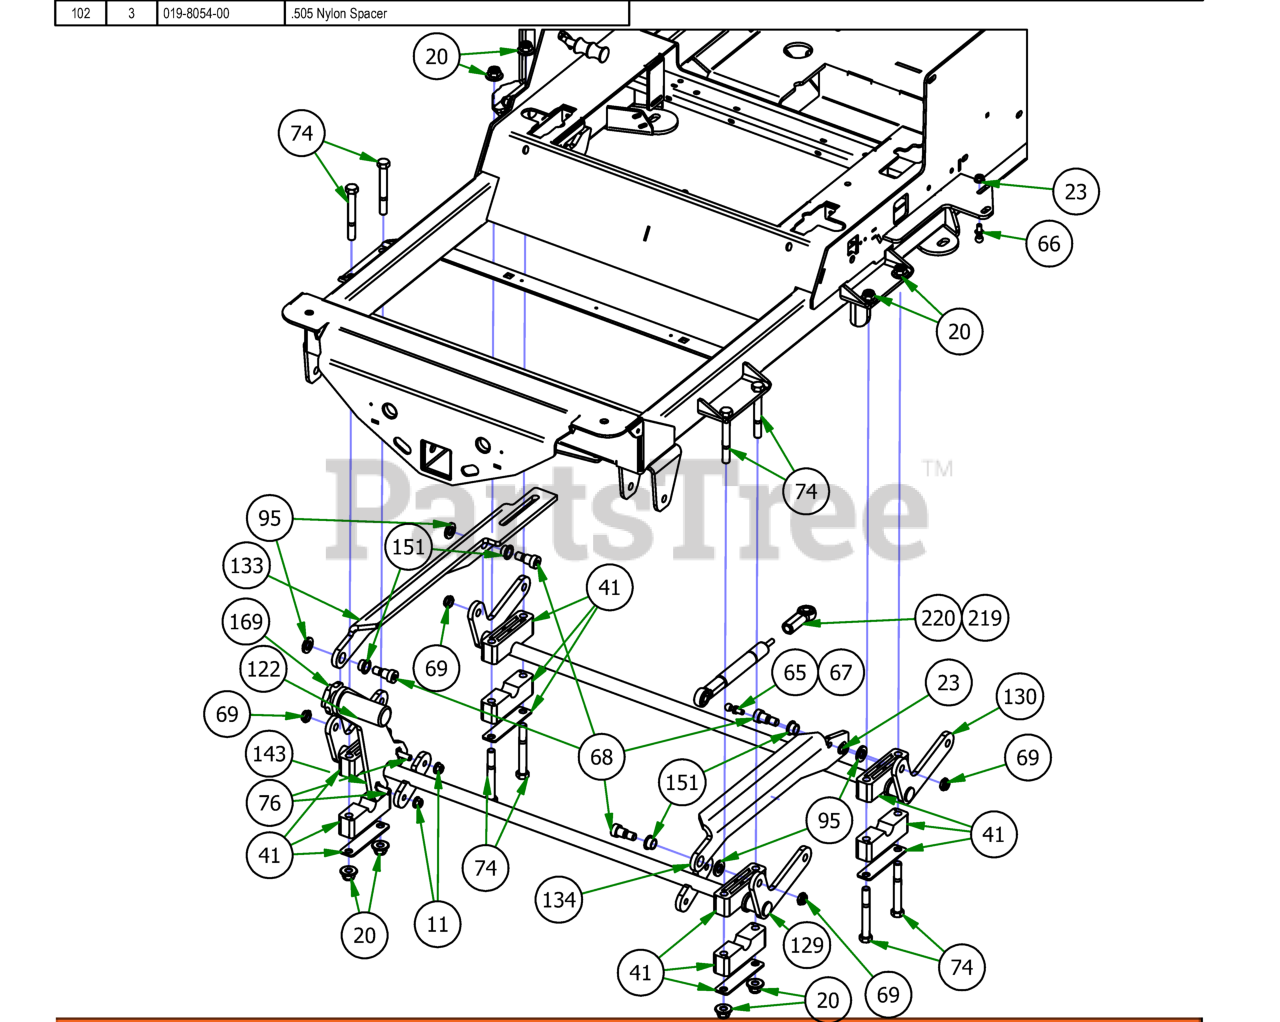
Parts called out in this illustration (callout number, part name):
11	3/8-16 NYLON INSERT FLANGE LOCKNUT (GR.F) ZINC
20	1/2-13 NYLON INSERT FLANGE LOCKNUT ZINC
23	5/16" Flange Nut
41	Pillow Block Assembly
65	13mm Damper Ball Stud-Steering
66	10mm Damper Ball Stud-Steering
67	10mm Damper Ball Stud-XP Linkage
68	5/8'' x 5/8'' Shoulder Bolt
69	1/2" Nylcock Nut (1/2 Jam)
74	1/2" x 4" Bolt (Grade 8)
76	3/8" x 1 1/4" Carriage Bolt
95	.635 ID X 1.120 OD X .140 THICK FLAT WASHER NYLON
122	Knurled Pedal
129	2019 Outlaw Actuator - Front
130	2019 Outlaw Actuator - Rear
133	2019 Actuator Linkage - Right
134	2019 Actuator Linkage - Left
143	Foot Lift Upright Lever
151	Bronze Bushing - SF - 2024-8
169	Foot Pedal Knob 1/2-13
204	2019 Renegade Gas Frame - Powdercoated
219	250lb Gas Spring - 61" Deck
220	300lb Gas Spring - 72" Deck
